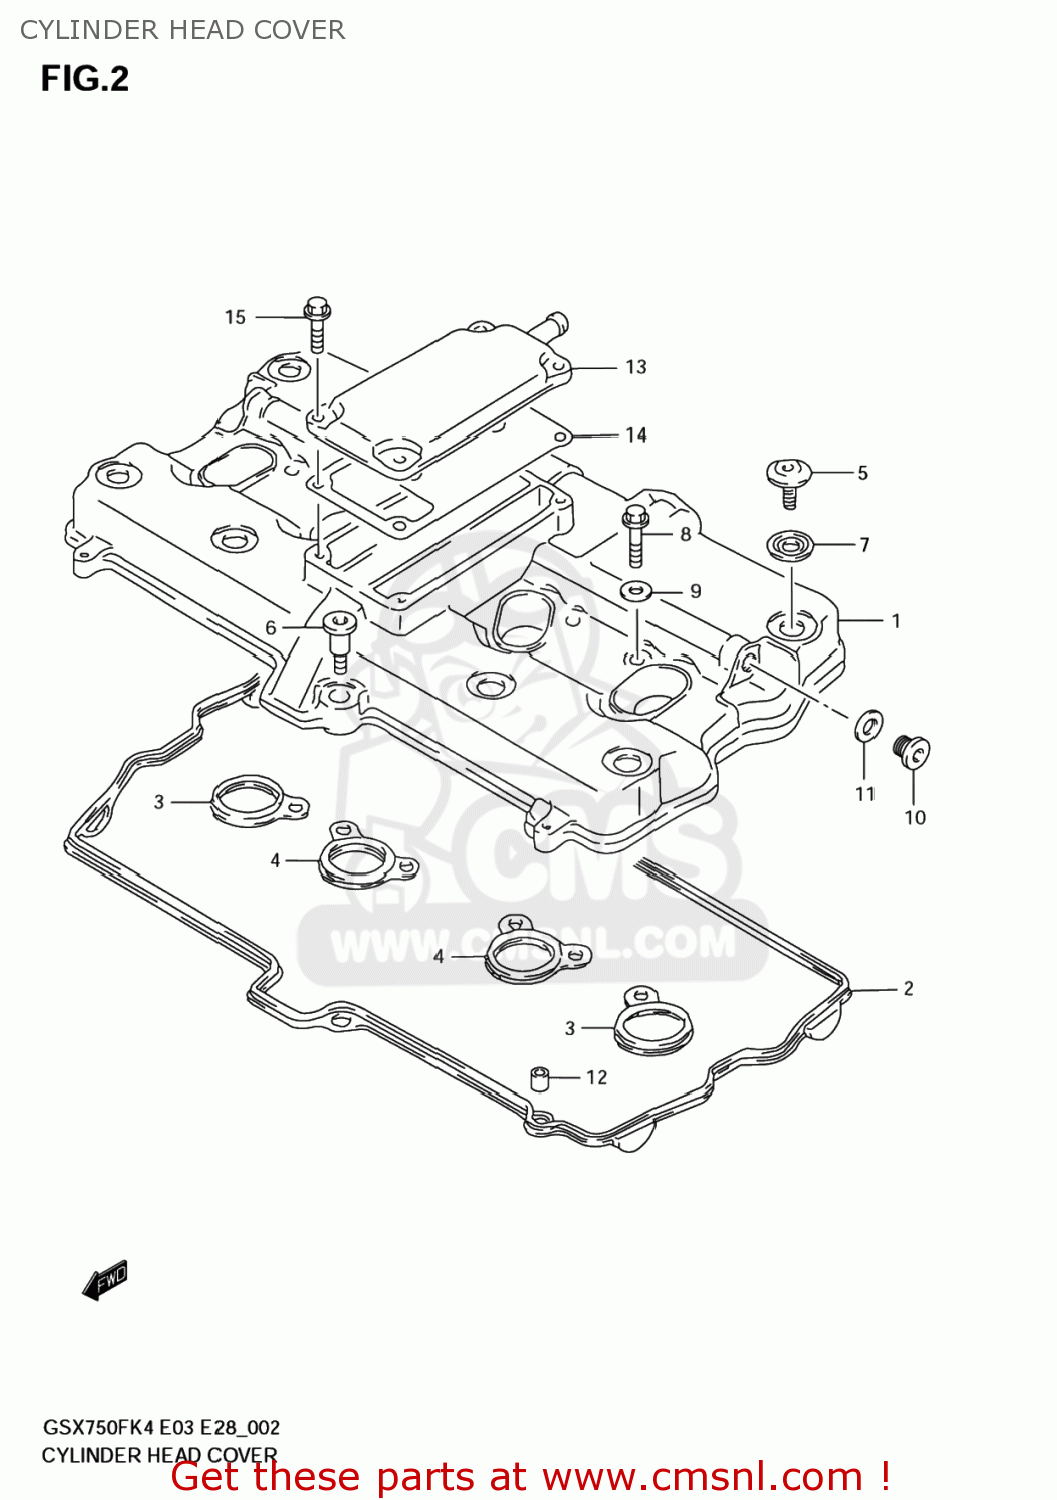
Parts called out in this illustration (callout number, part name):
1	COVER,CYLINDER HEAD
2	GASKET,CYLINDER HEAD COVER (NAS)
3	GASKET,HEAD COVER NO.2 (NAS)
4	GASKET,HEAD COVER NO.3 (NAS)
5	BOLT(7X17.5)
6	BOLT(7X31)
7	WASHER(10.6X25.5X2.3)
8	BOLT,HEAD COVER UNION(8X35)
9	GASKET(8.2X16X1) (NAS)
10	PLUG
11	GASKET(12.1X16.2X3.7) (NAS)
12	PIN
13	COVER,BREATHER
14	GASKET,BREATHER COVER (NAS)
15	BOLT
